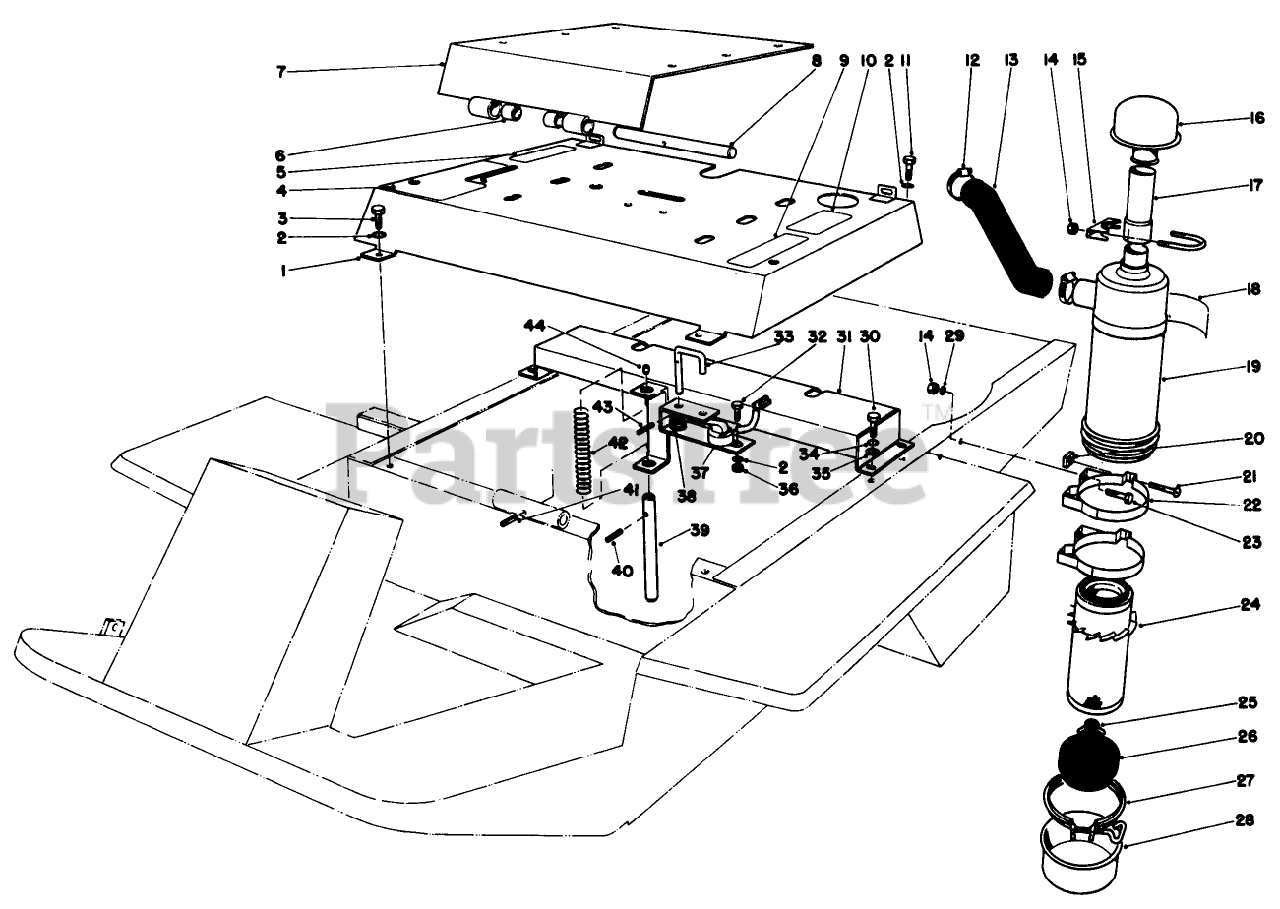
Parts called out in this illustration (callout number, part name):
2	SCREW-HH
3	SCREW THD 1/4 20 5/8
6	.503ID X .875LG BSHG
7	SEAT MTG WA
8	SHAFT-PIVOT, SEAT
10	DECAL-REFUELING
11	SCREW-HH
12	CLAMP-HOSE
14	NUT-HEX
15	CLAMP-MUFFLER
18	DECAL-INSTALLATION
19	AIR CLEANER ASM
20	NUT-SQUARE
21	SCREW
22	MOUNTING BAND ASM
23	SCREW-HH
25	NUT AND GASKET ASM
26	SKIRT-BAFFLE
27	CLAMP ASM
28	A/C CUP ASM
29	SCREW-HH
30	SCREW-HH
32	SCREW-HH
34	WASHER-LOCK
35	WASHER-FLAT
36	NUT-HEX
38	SPRING
39	PIN-SWITCH, SEAT
40	SCREW-HH
41	SCREW-HH
43	PIN-SPRING
44	PIN-PEDAL
